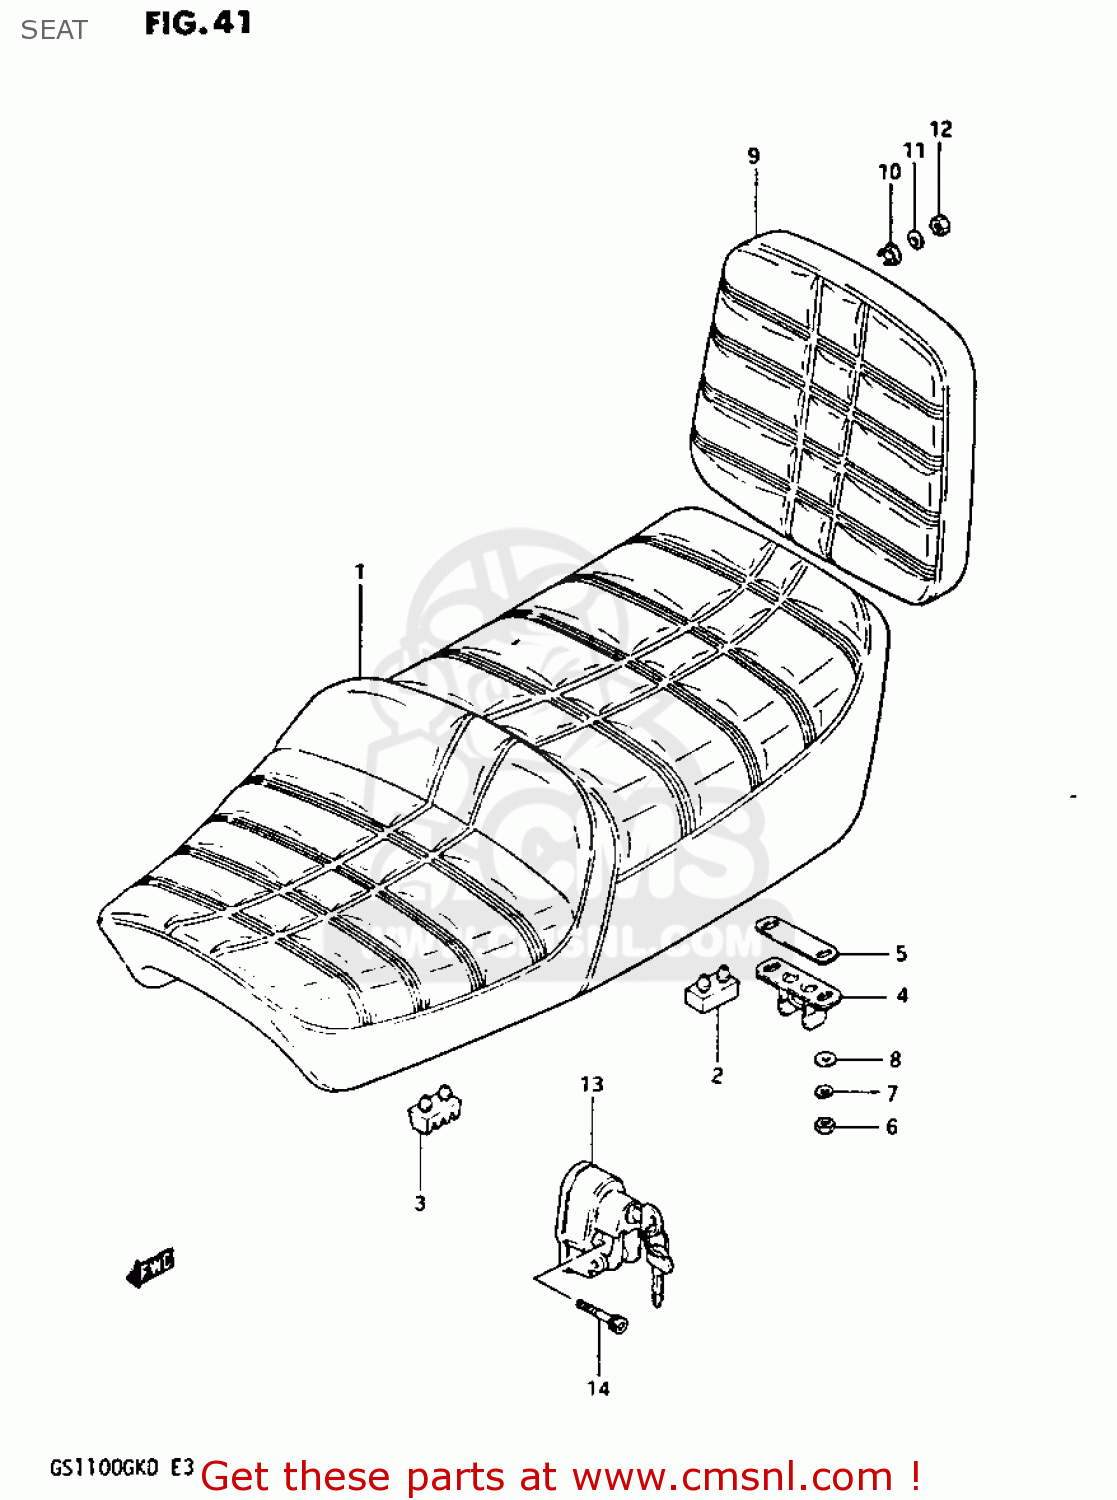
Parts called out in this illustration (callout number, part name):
1	SEAT ASSEMBLY
2	CUSHION(40X23X12.7)
3	CUSHION,SUPPORT(50X25X32)
4	STRIKER,SEAT LOCK
5	SHIM,SEAT LOCK STRIKER
6	NUT 6MM
7	WASHER,LOCK
8	WASHER
9	PAD ASSEMBLY,TAIL BOX
10	WASHER
11	WASHER,LOCK
12	NUT 6MM
13	LOCK ASSY,HELMET
14	BOLT
